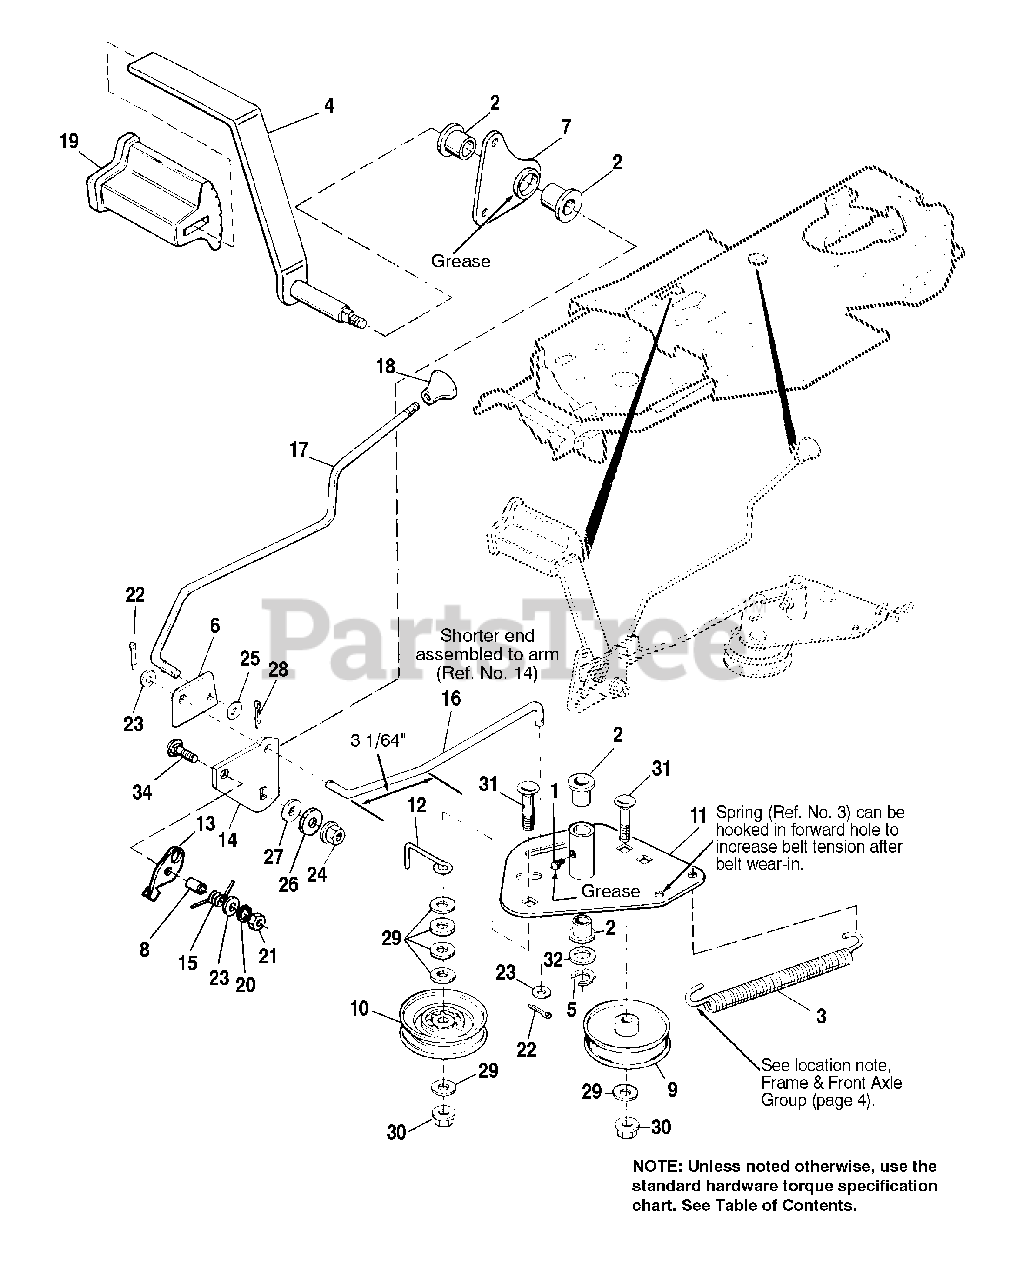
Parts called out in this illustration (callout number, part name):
1	FITTING, Grease
2	BUSHING, Plastic
3	SPRING, Drive
4	BRAKE PEDAL ASSY.
5	KLIPRING, 5/8
6	CAM, Parking Brake
9	PULLEY, Idler
11	ARM ASSY., Idler
13	SWITCH, Adaptor
14	ARM, Foot Pedal
15	SPRING, Torsion
16	ROD, Clutch, 5/16 Dia.
17	ROD, Parking Brake
18	KNOB, Plastic
19	PAD, Foot Pedal
20	LOCKWASHER, 5/16
21	NUT, Hex, 5/16-18
22	COTTER PIN
23	WASHER, Plain, 11/32
24	NUT, Hex, ESNA, 3/8-16
25	WASHER, Plain, 9/32
26	WASHER, Plain, 3/8
27	WASHER
28	COTTER PIN
29	WASHER, Plain, 13/32
30	NUT, Flange, Whizlock, 3/8-16
31	CARRIAGE BOLT, 3/8-16 x 1-3/4
32	WASHER, 5/8
34	CARRIAGE BOLT, 5/16-18 x 1-1/4
